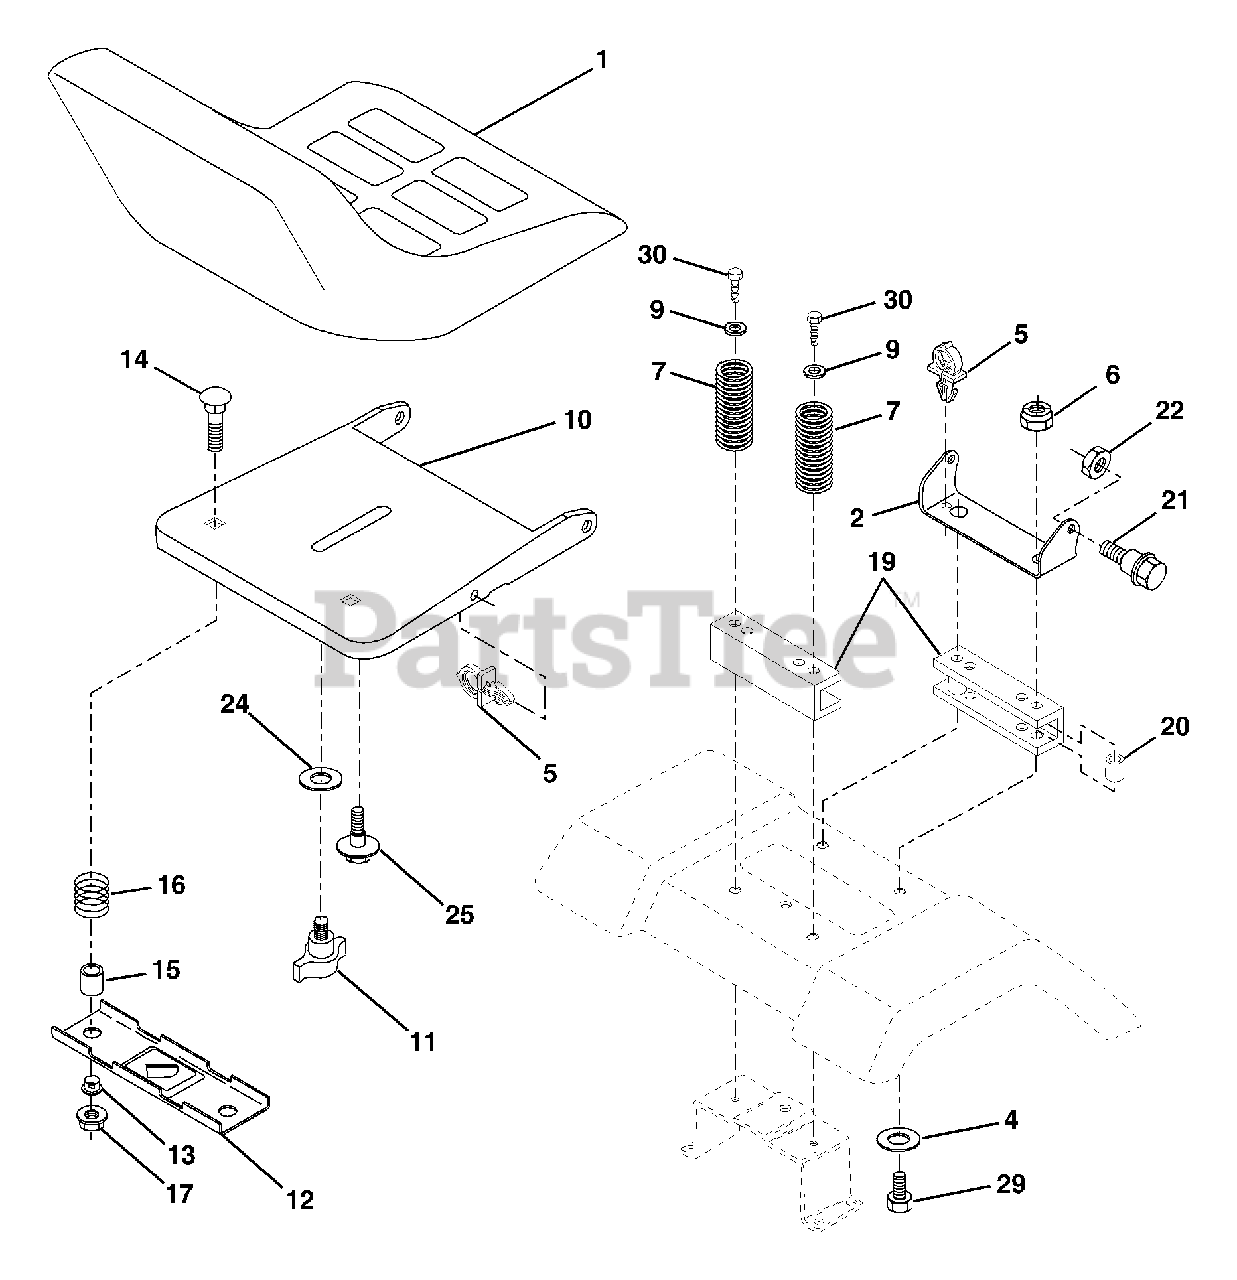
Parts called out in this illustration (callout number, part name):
1	Seat
2	Bracket Pivot Seat 8 720
3	Bolt Fin Hex 3/8-16 Unc x 1
4	Washer Flat 13/32 x 1 x 10 Ga.
5	Clip Push-In
6	Nut Hex w/Ins. 3/8-16 Unc
7	Spring Seat Cprsn 2 250 Blk Zi
10	Pan Seat
11	Knob Seat Adj. Wingnut
12	Bracket Mounting Switch
13	Bushing Snap Blk Nyl 50 Id
14	Bolt Rdhd Sqnk 1/4-20 x 1-1/2
15	Spacer Split
16	Spring Cprsn
17	Nut Lock 1/4 Lge Flg Gr 5 Zinc
21	Bolt Shoulder 5/16-18 Unc
22	Nut Hex Lock W/Ins 5/16-18
24	Washer 17/32 X 1-3/16 x 12 Ga.
25	Bolt Shoulder 5/16-18 x 62
27	Screw 3/8-16 x 1/2
28	Bolt 5/16-18 x 3/4
